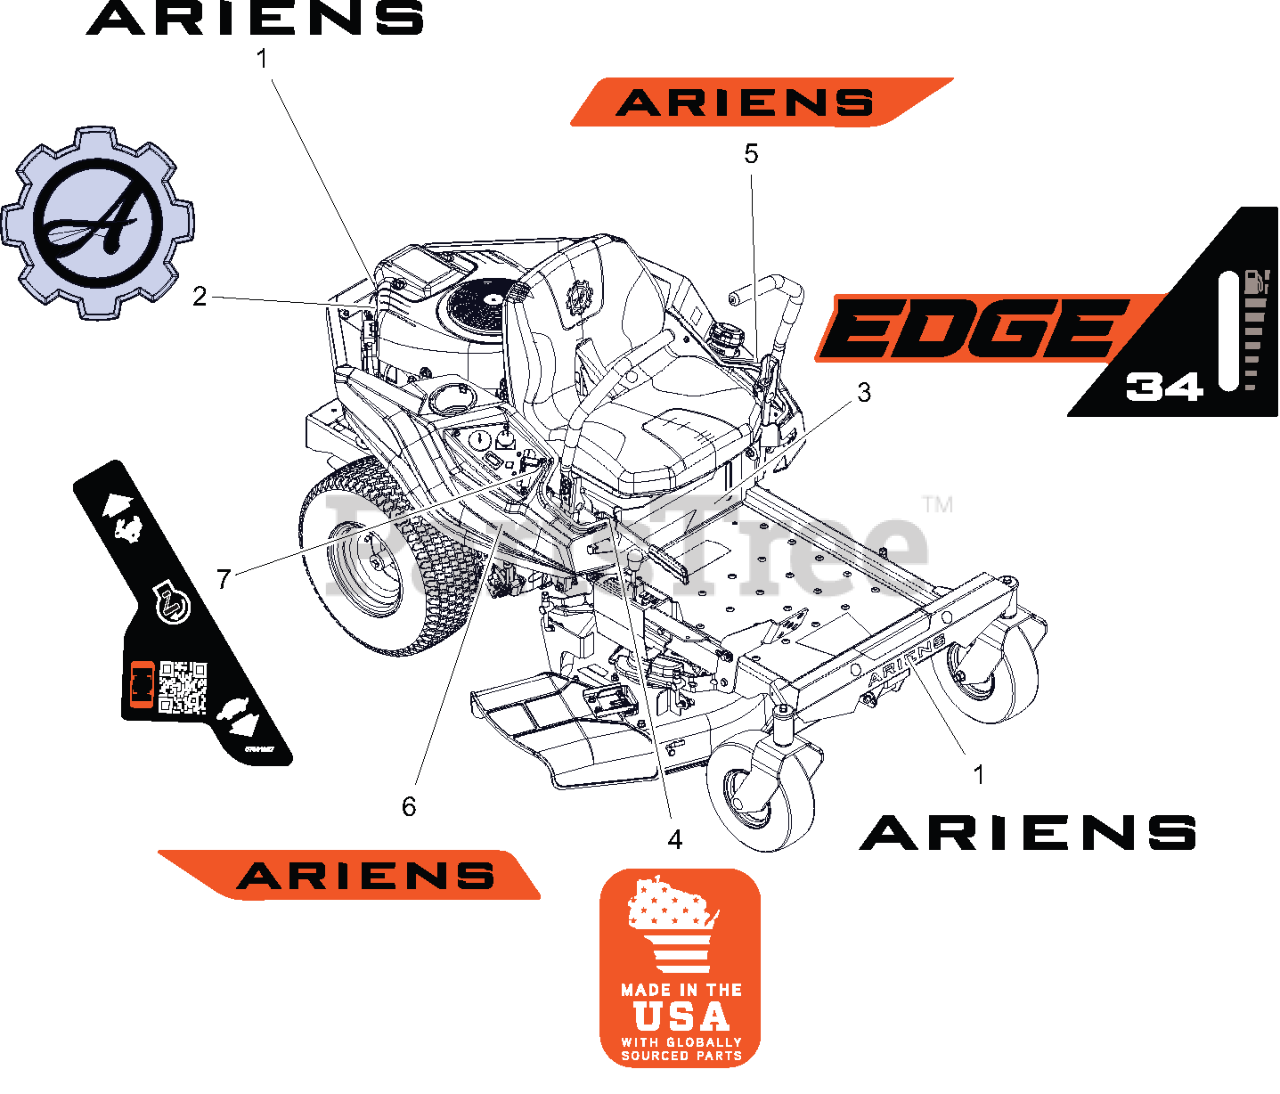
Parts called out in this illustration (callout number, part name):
1	DECAL- ARIENS 9.625" BLACK
2	DECAL- ARIENS GEAR BADGE
3	DECAL- EDGE 34 KICKPLATE
4	DECAL- MADE IN USA
5	DECAL- ARIENS (FENDER LH)
6	DECAL- ARIENS (FENDER RH)
7	DECAL- THROTTLE CONTROL EDGE
